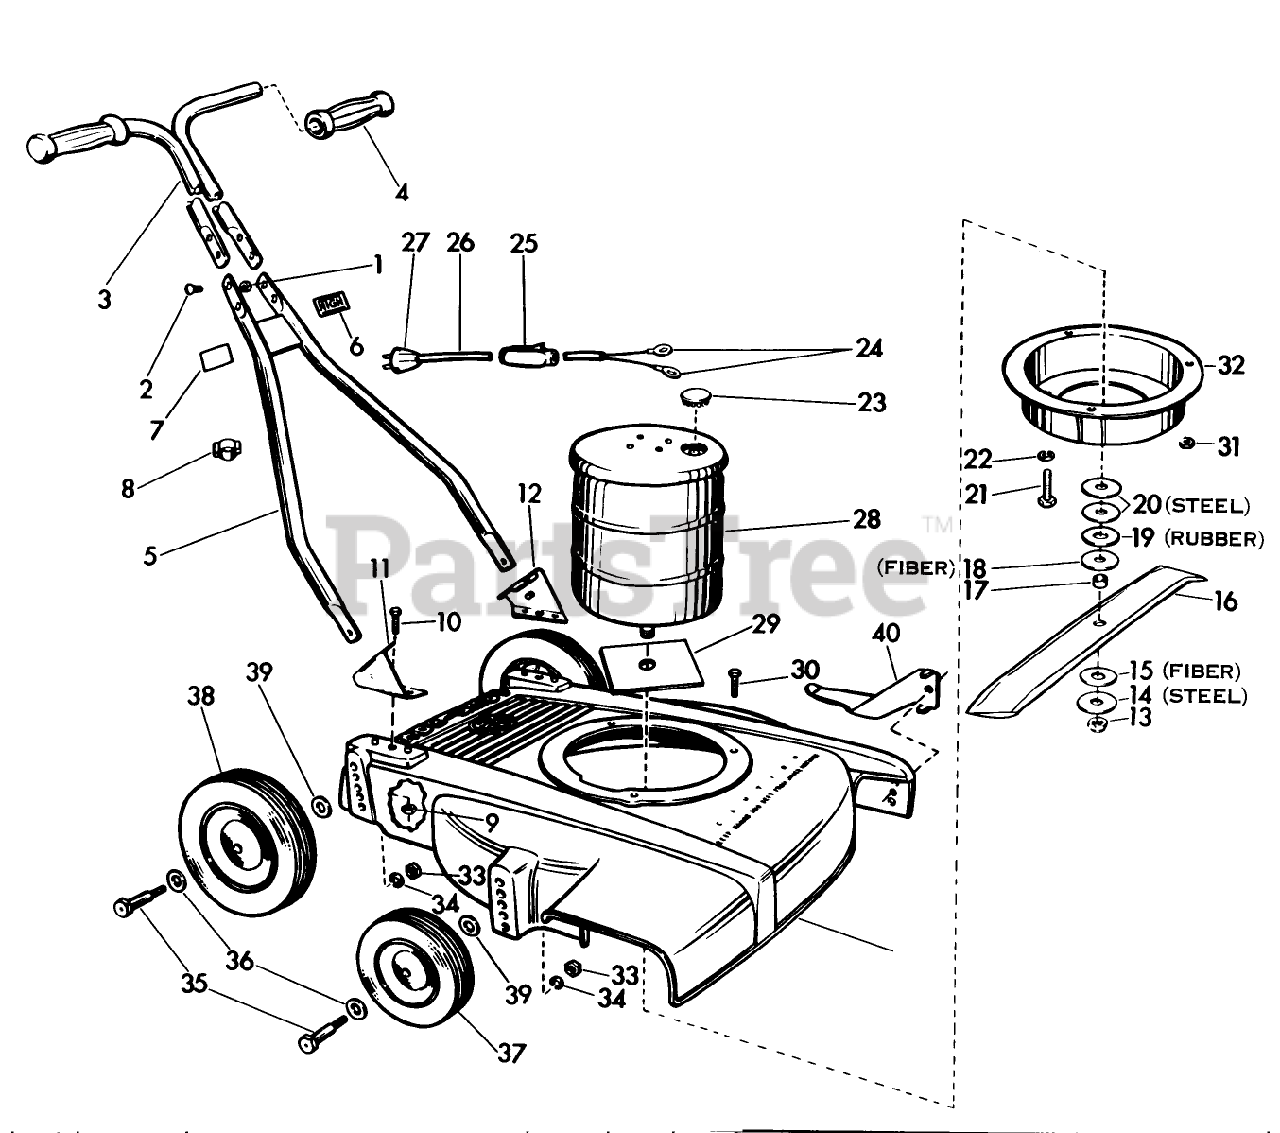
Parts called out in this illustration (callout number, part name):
1	STOP NUT
6	Decal-Handle "High"
7	Decal-Handle "Low"
8	Clip-Electric Cord
16	Blade-18"
17	Bushing-Blade
19	BLADE WASHER
21	Screw-Motor Mounting
22	WASHER, LOCK
23	Cap-Snap-on
24	Lug-Electric
25	Switch-Toggle
26	Plug-Electric
29	Shield-Dust
32	Plate-Adapter
34	WASHER, LOCK
40	Housing-18"
